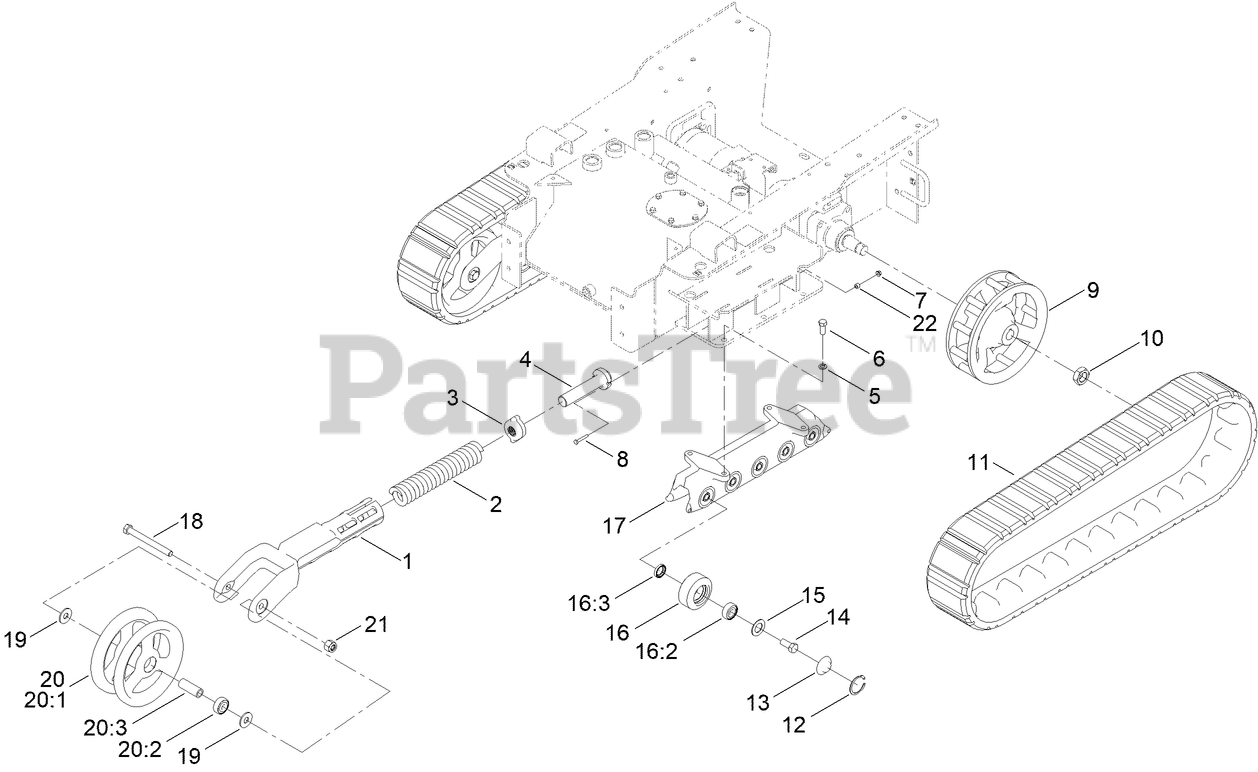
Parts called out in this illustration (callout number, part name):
1	ARM-TENSIONER
2	SPRING-COMPRESSION
3	BLOCK-TENSIONER
4	BOLT-TENSIONER
5	WASHER-LOCK
6	SCREW-HH
7	NUT-HHF
8	SCREW-HH
9	WHEEL-DRIVE
10	NUT-HEX
12	RING-SNAP, INTERNAL
13	CAP-WHEEL, BEARING
14	SCREW-HH
15	GASKET-BOGIE
16	ROAD WHEEL ASM
16:2	BEARING-BALL
16:3	SEAL-OIL
17	GUIDE-TRACK, TX NARROW
18	SCREW-HH
19	WASHER-FLAT
20	TENSIONER WHEEL ASM
20:1	WHEEL-TENSIONER
20:2	SPACER-WHEEL, TENSIONER
20:3	BEARING-BALL
21	NUT-HEX
22	SPACER
